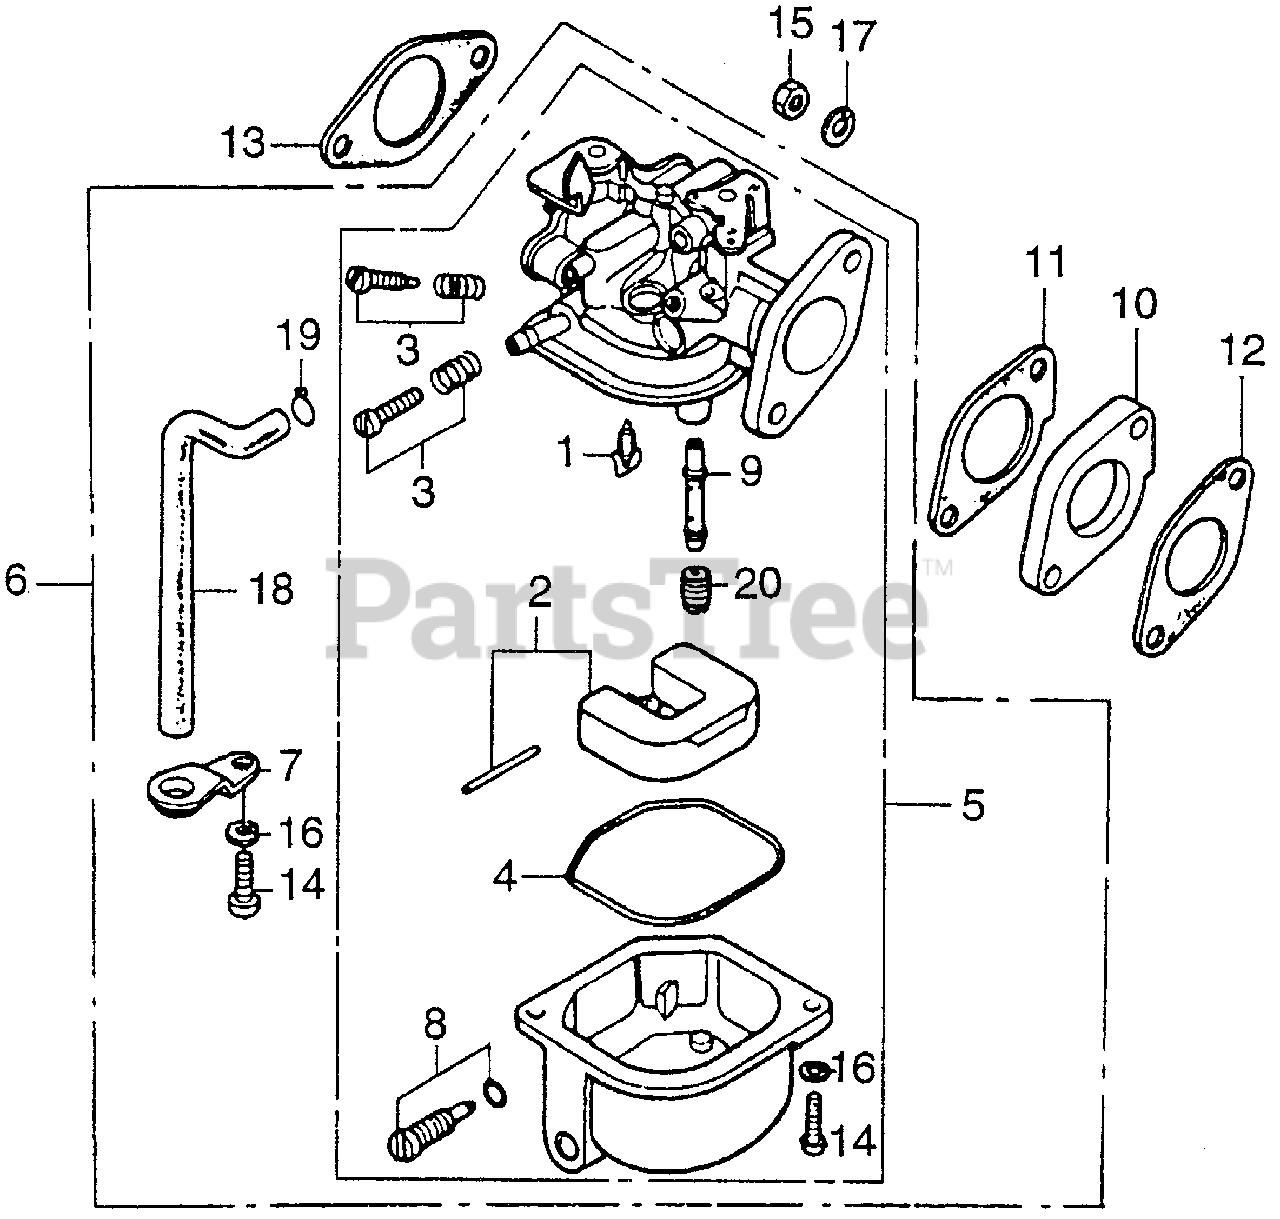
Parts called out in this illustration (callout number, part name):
1	VALVE SET, FLOAT (NOT AVAILABLE)
2	FLOAT SET
3	SCREW SET
4	O-RING (NOT AVAILABLE)
5	CARBURETOR ASSY. (NOT AVAILABLE)
6	CARBURETOR ASSY. (N/A: USE COMPONENT PARTS)
7	PLATE, STAY
8	SCREW, DRAIN
9	NOZZLE, MAIN
10	INSULATOR, CARBURETOR (NOT AVAILABLE)
11	GASKET A, CARBURETOR INSULATOR
12	GASKET B, CARBURETOR INSULATOR
13	GASKET, AIR CLEANER ELBOW
14	SCREW, PAN (4X12)
15	NUT, HEX. (6MM)
16	WASHER, SPRING (4MM)
17	WASHER, SPRING (6MM)
18	BULK HOSE, FUEL (3.5X3000) (3.5X120)
19	CLIP, TUBE (B7)
20	JET, AIR (#70) (NOT AVAILABLE)
